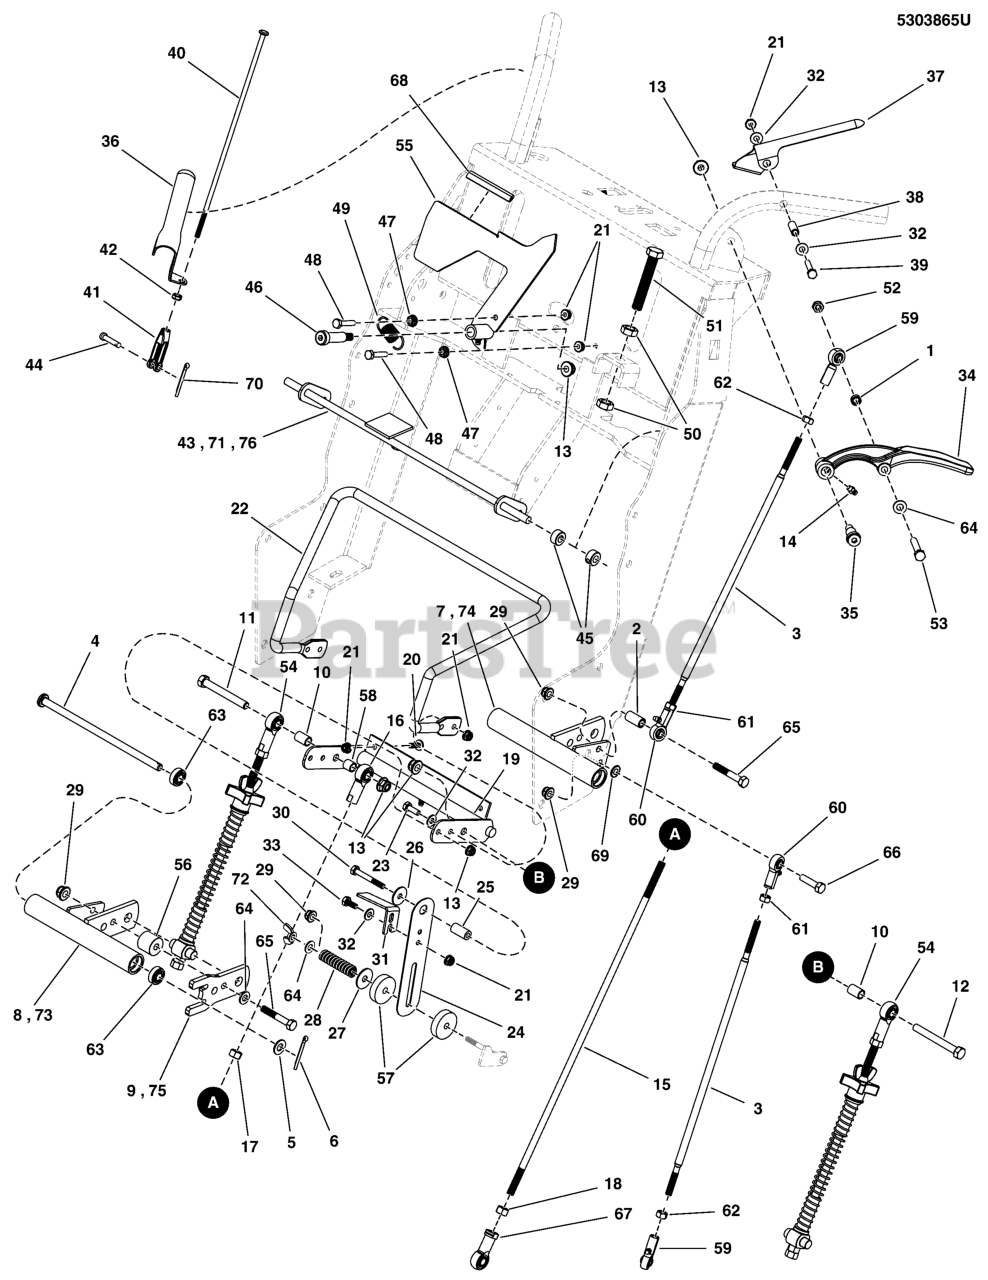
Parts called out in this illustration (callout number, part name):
1	SPACER, .33 X .50 X .25, PM, CZ
2	SPACER (.325 X .496 X 1.000)
3	ROD, 5/16-24 X 15.48, LH-RH, CZ
4	ROD, 3/8 X 8.49, HEADED
5	WASHER, 3/8 SAE
6	PIN, COTTER, 1/8 X 1-1/4
7	WELD, CENTER PIVOT HUB, LH - WALK - BLK
8	WELD, CENTER PIVOT HUB, RH - WALK - BLK
9	TAB, CONTROL PIVOT - BLK
10	SPACER, .38 X .50 X .75
11	BOLT, 3/8-16 X 3" GD5 CZ
12	BOLT, 3/8-16 X 2, GD5, CZ
13	NUT, 3/8-16 HEX NYLOCK FLANGE
14	GREASE FITTING, 1/4-28 STRAIGHT
15	ROD, 3/8-24, 19.00, LH-RH CZ
16	BALL JOINT, 3/8-24 FEMALE
17	NUT, 3/8-24 HEX
18	NUT, 3/8-24 HEX, LH
20	SCREW-TRUSS HD TORX DR 1/4-20X0.750 T27
21	NUT, 1/4-20 HEX NYLOCK FLANGE
22	BAR, SPEED CONTROL - BLK
23	BOLT, 1/4-20 X 3/4 GD5 CZ
24	PLATE, FRICTION CONTROL, SS
25	SPACER, .26 X .50 X 1.00
26	WASHER, 1/4 FENDER
27	WASHER, 5/16 FENDER
28	SPRING, COMP, .40 X .60 X 2.25, BLACK
29	NUT, 5/16-18 HEX NYLOCK FLANGE
30	BOLT, 1/4-20 X 2", GD5
31	BRACKET, SWITCH ENGAGEMENT - BLK
32	WASHER, 1/4 SAE
33	HHCS, 1/4-20 X 0.625, GR5, ZINC/CLEAR
34	HANDLE, REVERSING - BLK
35	BOLT, 3/8-16 X 1/2, 1.00 SHOULDER, CZ
38	SPACER, .26 X .38 X 1.25, CZ
39	BOLT, 1/4-20 X 1-3/4 GD5 CZ
40	ROD, OPC LINK, SNP PRO WB
42	HN, 1/4F GR5 YZ
43	WELD, OPC ROD, WALK - BLK
44	PIN, CLEVIS, 1/4 X 7/8, PLATED
45	COLLAR, 3/8 SET
46	BOLT-3/8-16 x 1-1/2, 1/2 SHOULDER
47	NUT, 1/4-20 HEX SERR. FLANGE
48	BOLT, 1/4-20 X 1-1/4 GD5 CZ
49	SPRING, EXT, 0.525 X 0.058 X 2.250 SS
50	NUT, 1/2-20 HEX JAM
51	BOLT, 1/2-20 X 2-1/2, FLT
52	NUT, 5/16-18 HEX NYLON LOCK
53	BOLT, 5/16-18 X 2-1/4 GD5 CZ
54	SEE MOTION CONTROL GROUP - SPRING ASSEMBLIES
55	WELD, SPEED INDICATOR, W25 - BLK
56	SPACER, .33 X 1.00 X .88, CZ
57	PAD, T-712 FRICTION MATERIAL
58	SPACER, .38 X .50 X .50
59	BALL JOINT 5/16-24 RH FEMALE BRONZE RACE
60	BALL JOINT 5/16-24 LH FEMALE BRONZE RACE
61	NUT, 5/16-24 HEX, LH
62	NUT, 5/16-24 HEX
63	BEARING, .375" ID X .875" OD X .341" THK
64	WASHER, 5/16" SAE
65	BOLT, 5/16-18 X 2 GD5 CZ
66	BOLT, 5/16-18 X 1-1/4 GD5 CZ
67	BALL JOINT, 3/8-24 FEMALE, LH
68	U-CHANNEL, RPVC #6236 X 4"
69	WAHSER, 5/16 F436 FLAT
70	PIN, 3/32 X 0.750, COT, ZINC/CLEAR
71	WELD, OPC ROD, WALK - BLK
72	NUT, Wing, 5/16-18
73	WELD, W25 CONTROL PIVOT, RH - BLK
74	WELD, W25 CONTROL PIVOT, LH - BLK
75	TAB, PIVOT, W35 - BLK
76	WELD, OPC ROD, WALKBEHIND - BLK
